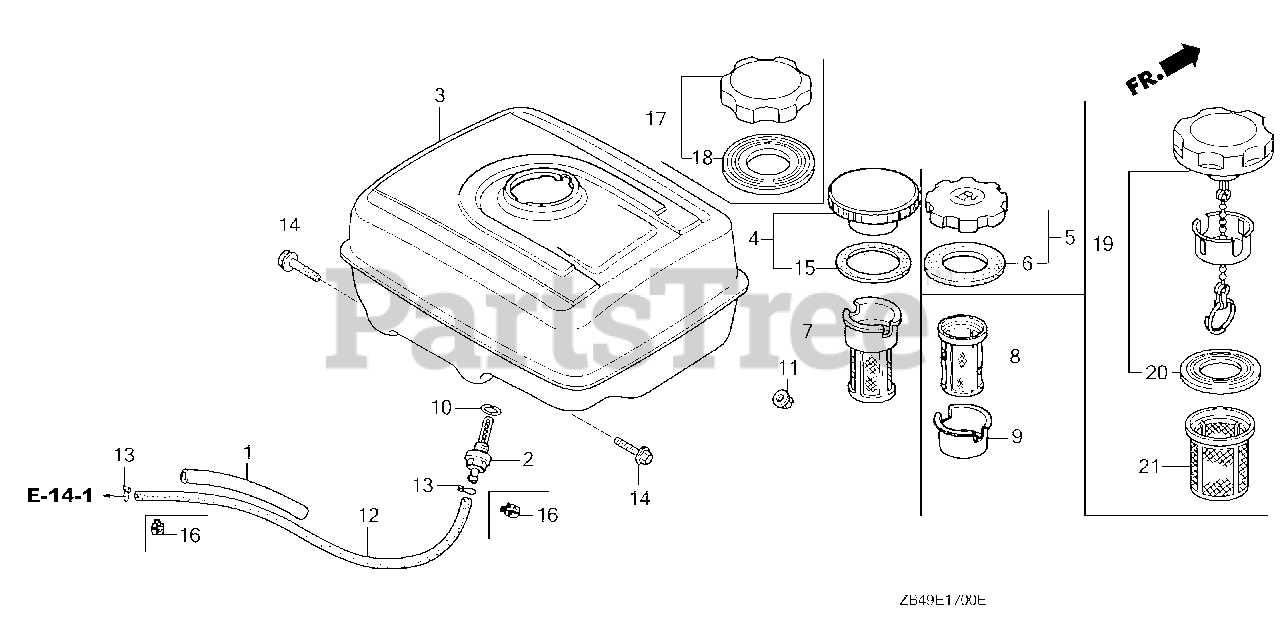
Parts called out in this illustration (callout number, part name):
1	RUBBER, SUPPORTER (107MM)
2	JOINT, FUEL TANK (NOT AVAILABLE)
2	JOINT, FUEL TANK
3	TANK, FUEL *R280* (POWER RED)
5	CAP, FUEL FILLER (BLACK)
6	GASKET, FUEL FILLER CAP (39X58X3)
7	FILTER, FUEL
10	O-RING (14MM) (ARAI)
10	O-RING (14MM) (NOK)
11	NUT, FLANGE (8MM)
12	BULK HOSE, FUEL (4.5X3000) (4.5X222)
13	CLIP, TUBE (B8)
14	BOLT, FLANGE (8X25)
